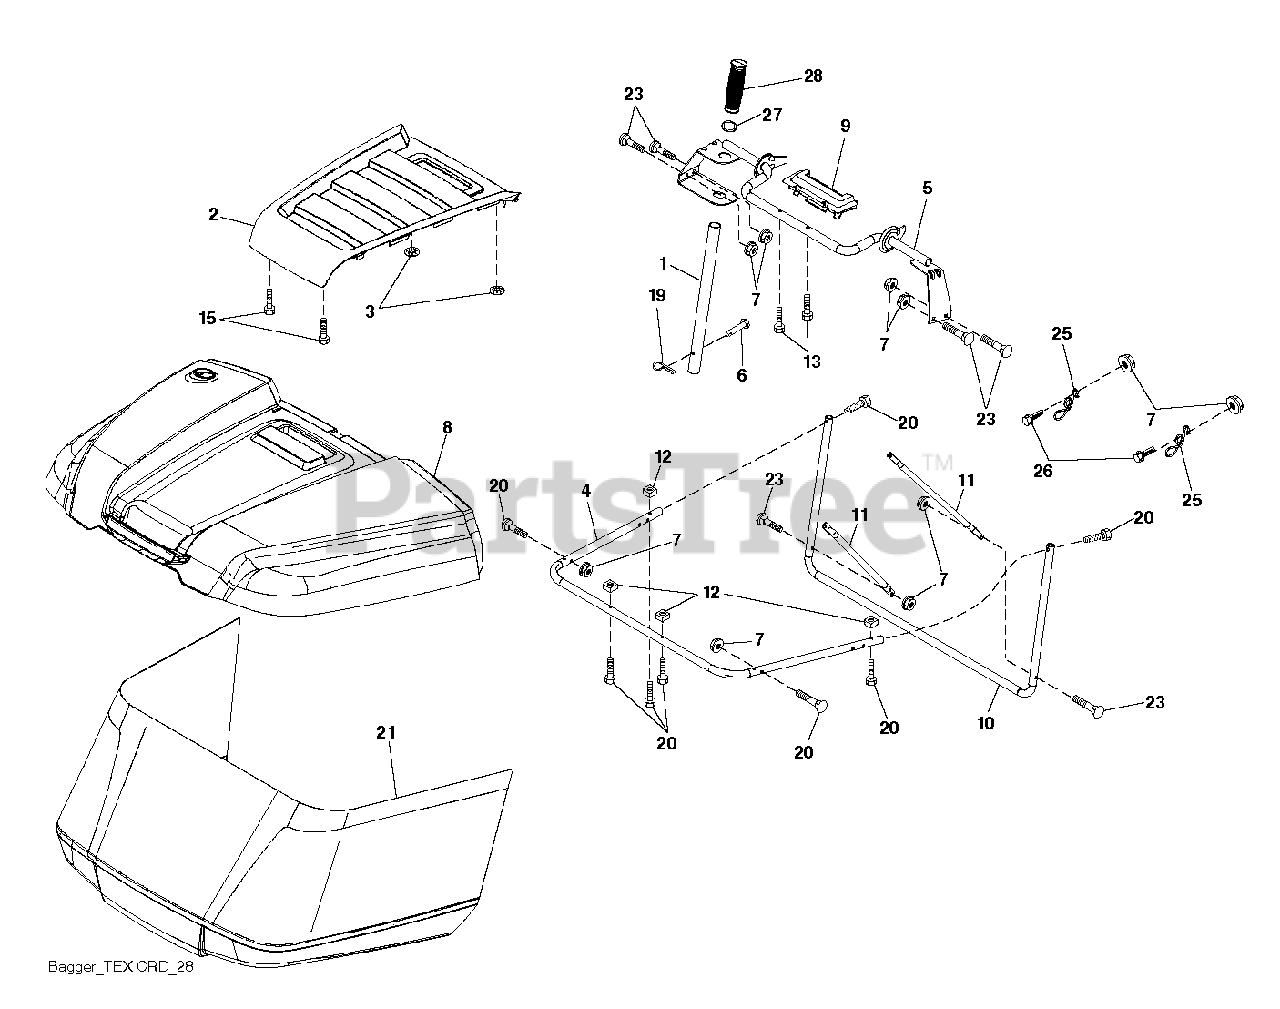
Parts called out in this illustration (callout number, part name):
1	TUBE.HANDLE.BAGGER.CRD/SRD.BLA
2	APPLIQUE.TOP.BAG.SRD.ORANGE
3	NUT.PUSH.156
4	SUBASM.TOP.TUBE.TEX.CRD
5	FRAME.ASM.TOP.BAGGER.SRD
6	RIVET,DRILLED
7	NUT T
8	BAGGER.TOP.SRD.APPLIQUE
9	INSERT.HANDLE.BAGGER.(2 2)
10	FRAME FRAME.FRONT.TEX.CRD
11	BRACE BRACE SIDE TUBE
12	NUT.SQUARE.1/4
13	SCREW.1/4X1.150.HXWSH
15	SCREW,#8.FLAT.HEAD.DRILL.TIP
19	PIN.COTTER.5/16.BOW TI
20	SCREW.HEXCAP.1/4-20X1.375(2 2)
21	BAG SUBASM. TEX CRD GEN 2 HUSQ
25	SPRING.LATCH.BAGGER.SRD
26	SCREW HEX CRT
27	RB GROMMET.RUBBER.SRD
28	GRIP.HANDLE.BLACK
